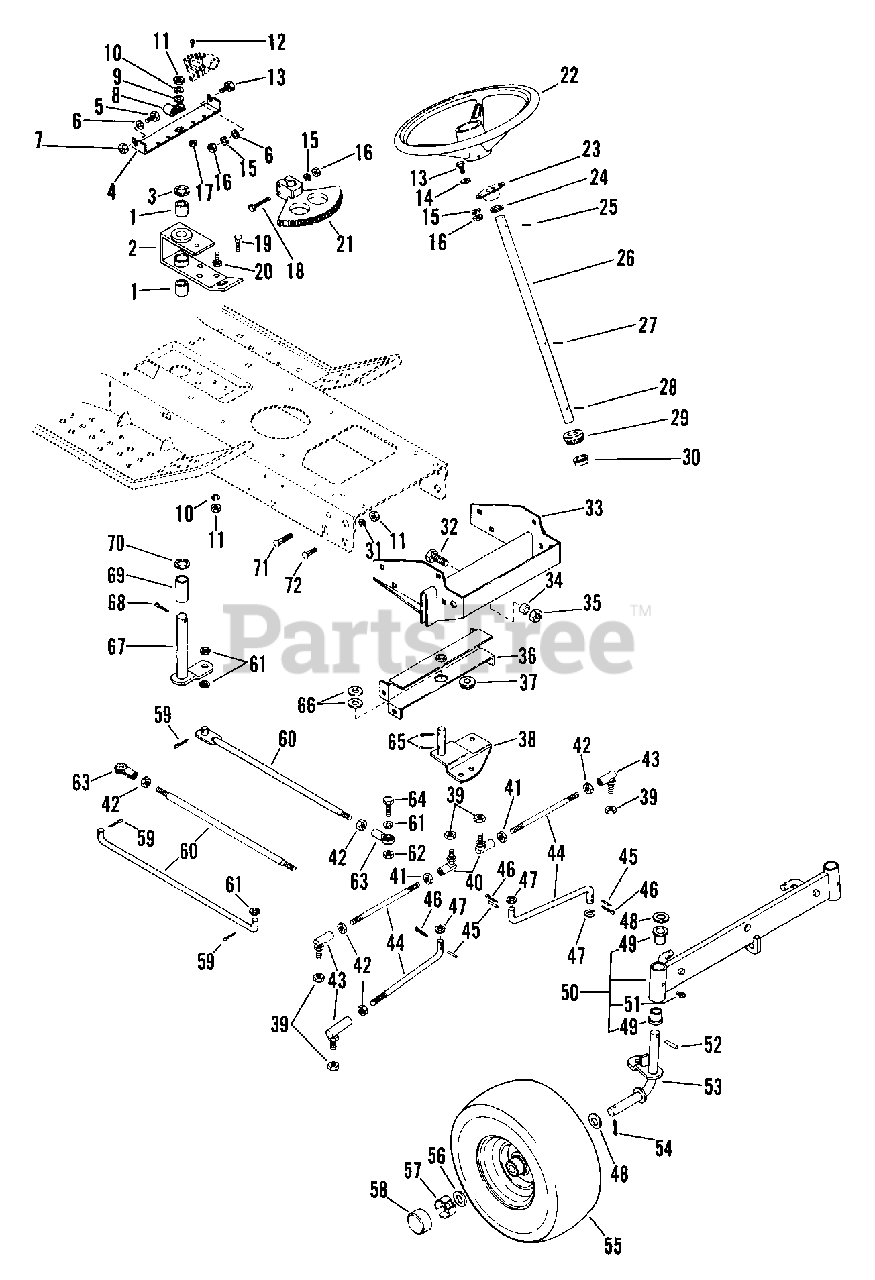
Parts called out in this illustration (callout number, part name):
1	BSHG-SLV .750X1.000X.750 HX SB
2	STEERING BRACKET
3	WSHR-FL-STL .880X1.250X.062
5	BLT-HEX .31-18X1.25 PL GR5
6	WSHR-FL-STL .323X.625X.062 PL
7	NUT-LK-TOP .312-18 GR C PL
9	WSHR-FL-STL.406X.812X.065PL
10	WSHR-LK .375X.115 HVY PL
11	NUT-HEX .375-16
12	SCR-MCH 10-24X.62 SLRH PL
13	BLT-HEX .31-18X.75 PL GR5
14	WSHR-FL-STL.312X.734X.065PL
15	WSHR-LK .312X.097 PL HVY
16	NUT-HEX .312-18
17	NUT-KEPS 10-24 PL
18	BLT-HEX .31-18X1.75 PL GR2
19	BLT-RDHDSQNK .38-16X1.25 PL
20	BLT-HEX .38-16X1.00 PL
21	STEERING BEVEL GEAR
22	STEERING WHEEL
23	BRG-FLG .751X2 HOLESX.81
24	WSHR-FL-STL .754X1.125X.062 PL
25	PIN-ROLL .250X1.75
28	PIN .249X1.125 DRIV-LOK SP
29	PINION GEAR-STEERING
30	CARTON, 31.75 X 17 X 5" 275DW
31	WSHR-LK .375X.094 MED PL
32	BLT-HEX .50-13X1.25 PL GR5
33	FRONT AXLE SUPPORT
34	SPACER .531X.748X.524
35	NUT-LK-CROWN .50-13 GR C PL
36	STEERING PIVOT CHANNEL
37	FLANGE BUSHING
38	STEERING PIVOT
39	NUT-LK .50-20 PL
39	NUT-LK .375-24 PL
40	BALL JOINT-LH
41	NUT L.H. THD .375-24 PL
42	NUT-JAM .50-20 PL
42	NUT .375-24 PL
43	BALL JOINT R.H.
43	BALL JOINT-RH
44	DRAG LINK
44	TIE ROD
45	PIN-ROLL .125X1.00
46	PIN-COTR .12X1.0 PL
47	WSHR-FL-STL .520X.827X.062 YZ
48	WSHR-FL-STL .755X1.375X.093
49	BSHG-FLG .750X1.000X.750X1.250
50	AXLE W/BUSHINGS
51	SPIN DRIVE ZERK FITTING
52	PIN-ROLL .250X1.25
53	LEFT SPINDLE WELDMENT
53	SPINDLE-LH
53	RIGHT SPINDLE WELDMENT
53	SPINDLE-RH
54	PIN-COTR .25X1.50 ST PL
55	T/WHL ASSY
55	TIRE
55	BRG-BALL .752X1.50X.50
56	WSHR-FL-STL .755X1.375X.062 PL
57	SPINDLE CUP
58	HUB CAP
59	PIN-COTR .12X1.0 PL
60	STEERING LINK
60	DRAG LINK
61	WSHR-FL-STL .505X.880X.072 PL
61	WSHR-FL-STL .390X.750X.125 PL
61	WSHR-FL-STL .520X.827X.062 YZ
62	NUT-LK TOP .375-16 GR C YWZC
63	ROD END, .38 RH
64	BLT-HEX .38-16X1.25 PL GR5
65	PIN-COTR .12 X 1.25 PL
66	WSHR-FL-STL.656X1.312X.095 PL
67	ARM & SHAFT
68	PIN-COTR .18X1.25 PL
69	SPACER .780X.900X2.094
70	WSHR-FL-STL .875X1.250X.075
71	BLT-RDHDSQSHNK .38-16X1.00 PL
72	BLT-RDHDSQNK .38-16X.75 SHT PL
